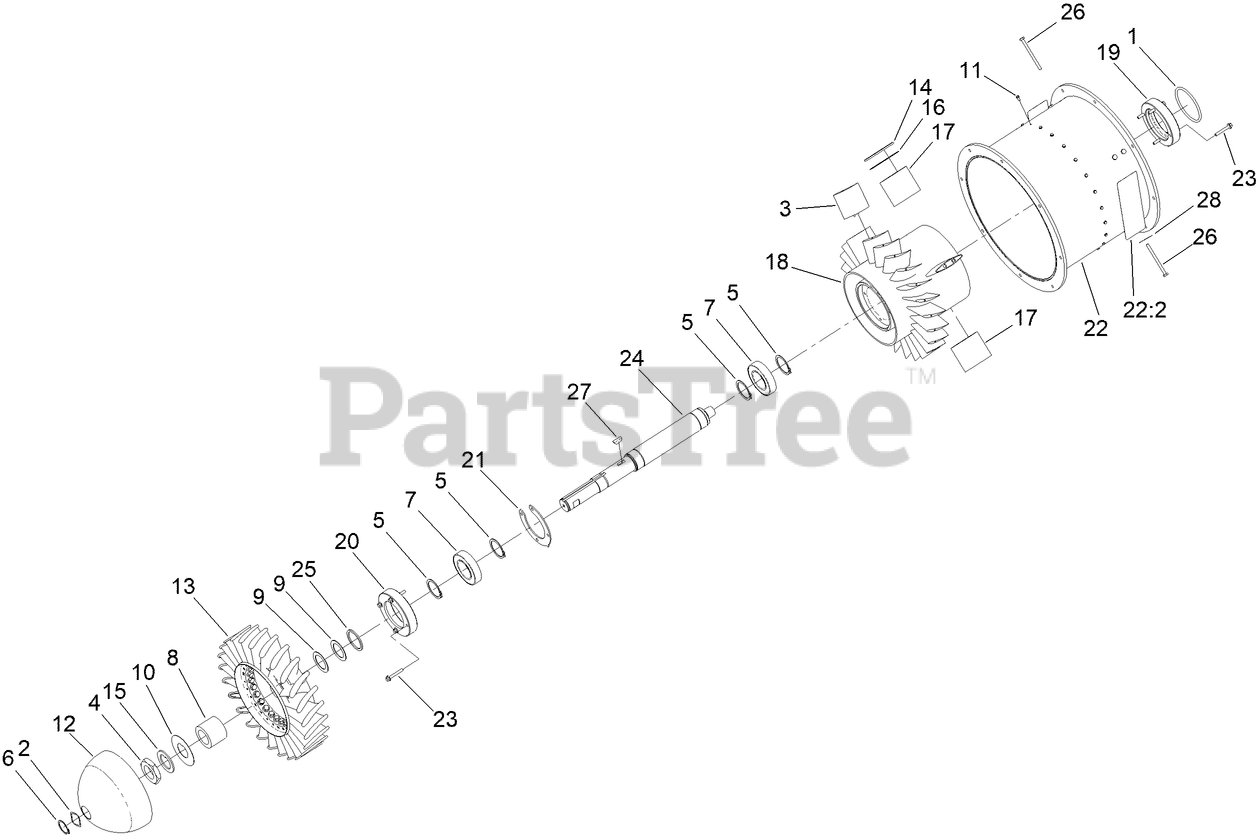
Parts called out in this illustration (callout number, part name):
1	O-RING
2	WASHER-WAVEY
3	VANE-STATOR
5	RING-SNAP, EXT
6	RING-SNAP, EXT
7	BEARING-BALL
8	SPACER
9	WASHER
10	WASHER-TAB
11	SCREW-HHF
12	CAP-FRONT
14	SPACER-FIN
15	WASHER-TAB
16	SPACER-FIN
17	MOUNT-FIN
18	INNER HOUSING
19	END-ORING
20	BEARING-CAP
21	END-CAP
22	VERTICAL HOUSING ASM
22:2	DECAL-DANGER
23	SCREW-HHF
24	SHAFT-FAN
25	SPACER-BEARING
26	SCREW-HH
27	KEY-WOODRUFF
28	TAB-LOCKING
